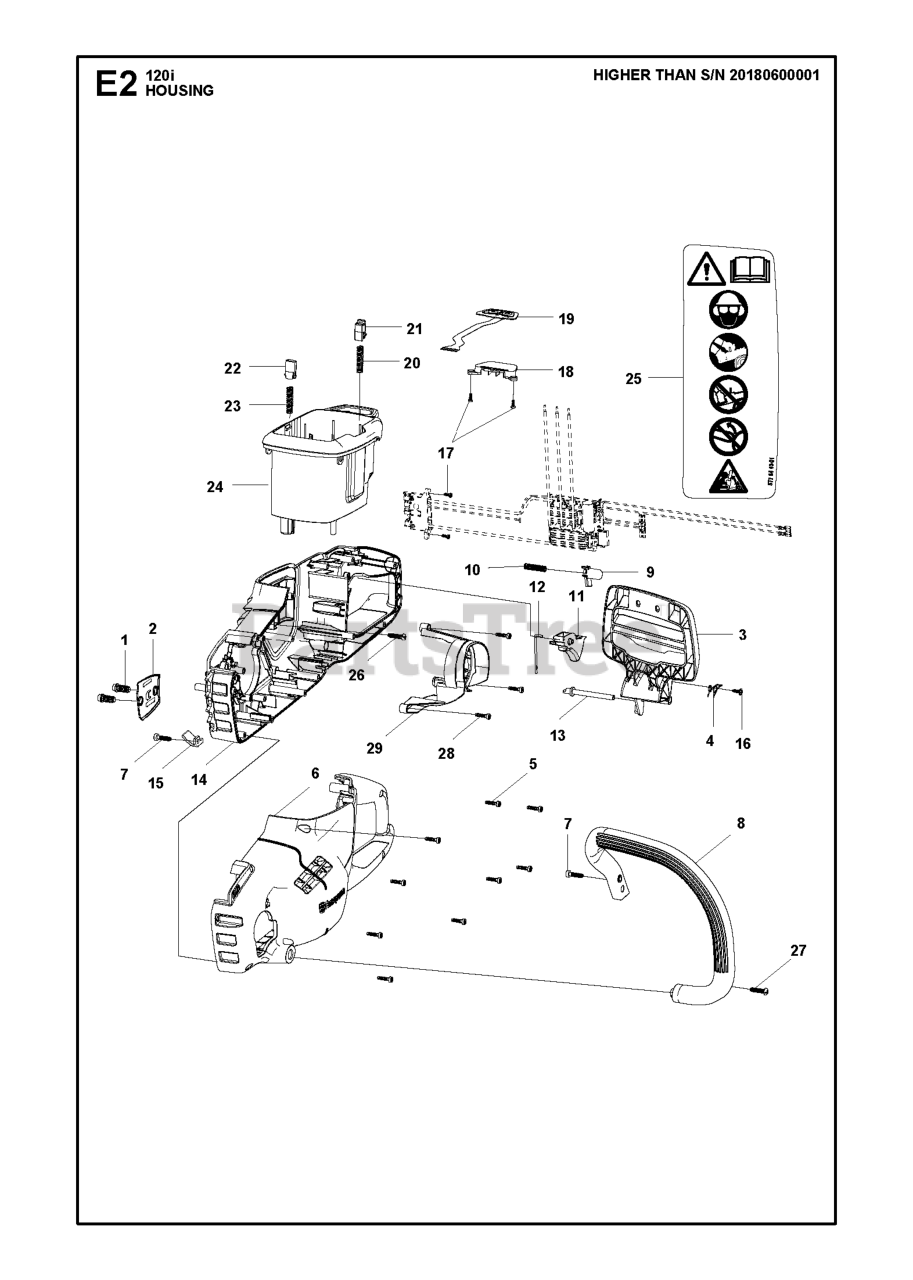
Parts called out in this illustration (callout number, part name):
1	SCREW ST8X16
3	BRAKE HAND GUARD
4	SPRING BRAKE CUT OFF POWDER
5	SCREW ST4X16
6	HOUSING LEFT - PAINTING
7	SCREW ST4.8X18
8	FRONT HANDLE
9	BUTTON LOCK OFF
10	SPRING LOCK OFF BUTTON
12	LEVER TRIGGER
13	PIVOT HAND GUARD
14	HOUSING RIGHT ASSEMBLY
15	CHAIN CATCHER
16	SCREW SCREW MT3X10 36V
17	SCREW ST3X8
18	BRACKET KEY PAD
19	KEYPAD CHAINSAW
20	SPRING PUSH BUTTON
21	PUSH BUTTON
22	PUSH BUTTON FRONT
23	SPRING PUSH BUTTON
24	BATTERY BOX
26	SCREW ST3X16
27	SCREW
28	SCREW ST4X12
